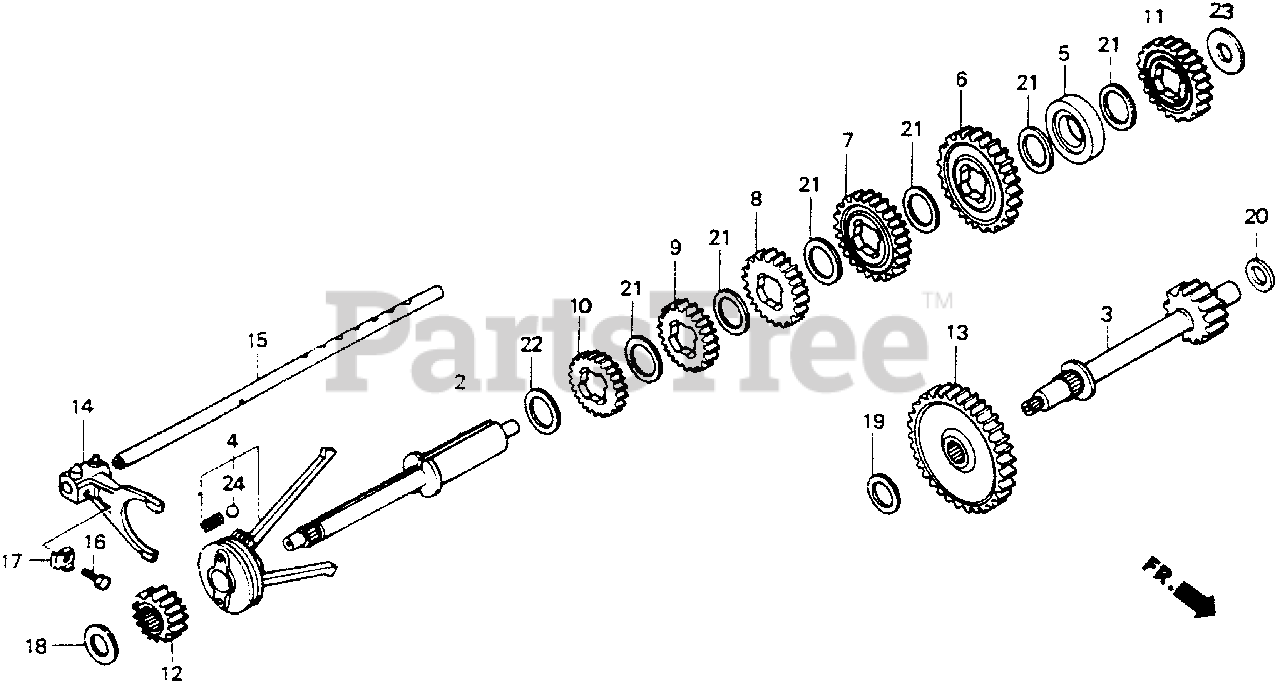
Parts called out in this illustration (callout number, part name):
1	SPRING, CHANGE KEY
2	SHAFT, CHANGE
3	COUNTERSHAFT
4	HOLDER, KEY
5	POSITIONER, NEUTRAL
6	GEAR, CHANGE LOW (48T)
7	GEAR, CHANGE SECOND (43T)
8	GEAR, CHANGE THIRD (37T)
9	GEAR, CHANGE FOURTH (34T)
10	GEAR, CHANGE FIFTH (32T)
11	GEAR, REVERSE CHANGE (41T)
12	GEAR, COUNTERSHAFT DRIVE (16T)
13	GEAR, COUNTERSHAFT DRIVEN (49T)
14	FORK, SHIFT
15	SHAFT, SHIFT FORK
16	BOLT, SHAFT FORK SETTING
17	WASHER, LOCK (6MM)
18	WASHER, THRUST (15MM)
19	WASHER, THRUST (20MM)
20	WASHER, THRUST (18MM)
21	WASHER, DISTANCE (2MM)
22	WASHER, DISTANCE (1MM)
23	WASHER, CHANGE THRUST
24	BALL, STEEL (#10) (5/16)
